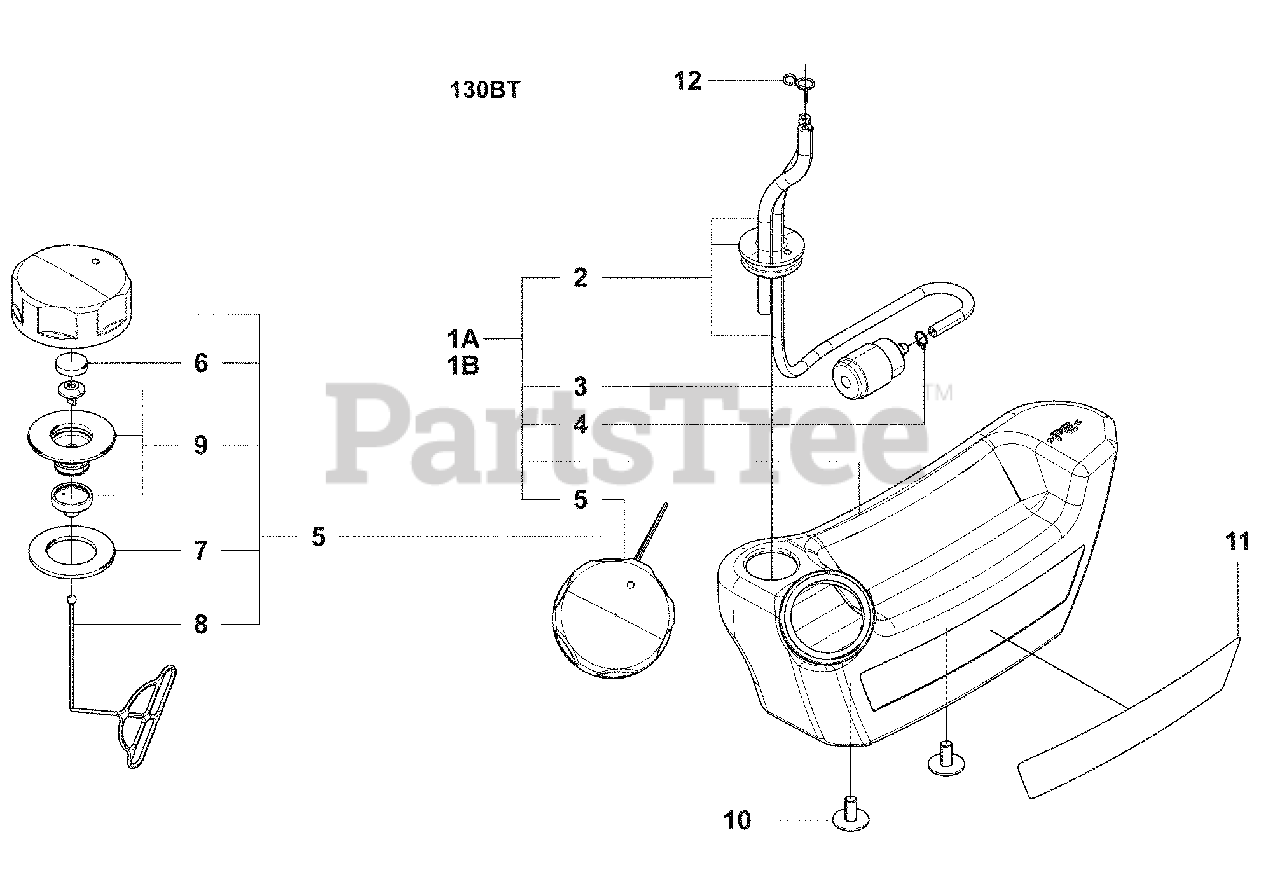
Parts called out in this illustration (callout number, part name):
1A	Tank, A
1B	Tank Assembly Evp
2	Pipe, Complete
3	Fuel Filter Assembly
4	Clip
5	Fuel Cap Assembly
6	Air Filter
7	Packing
9	Holder, A
11	LABEL TANK
12	Clip
